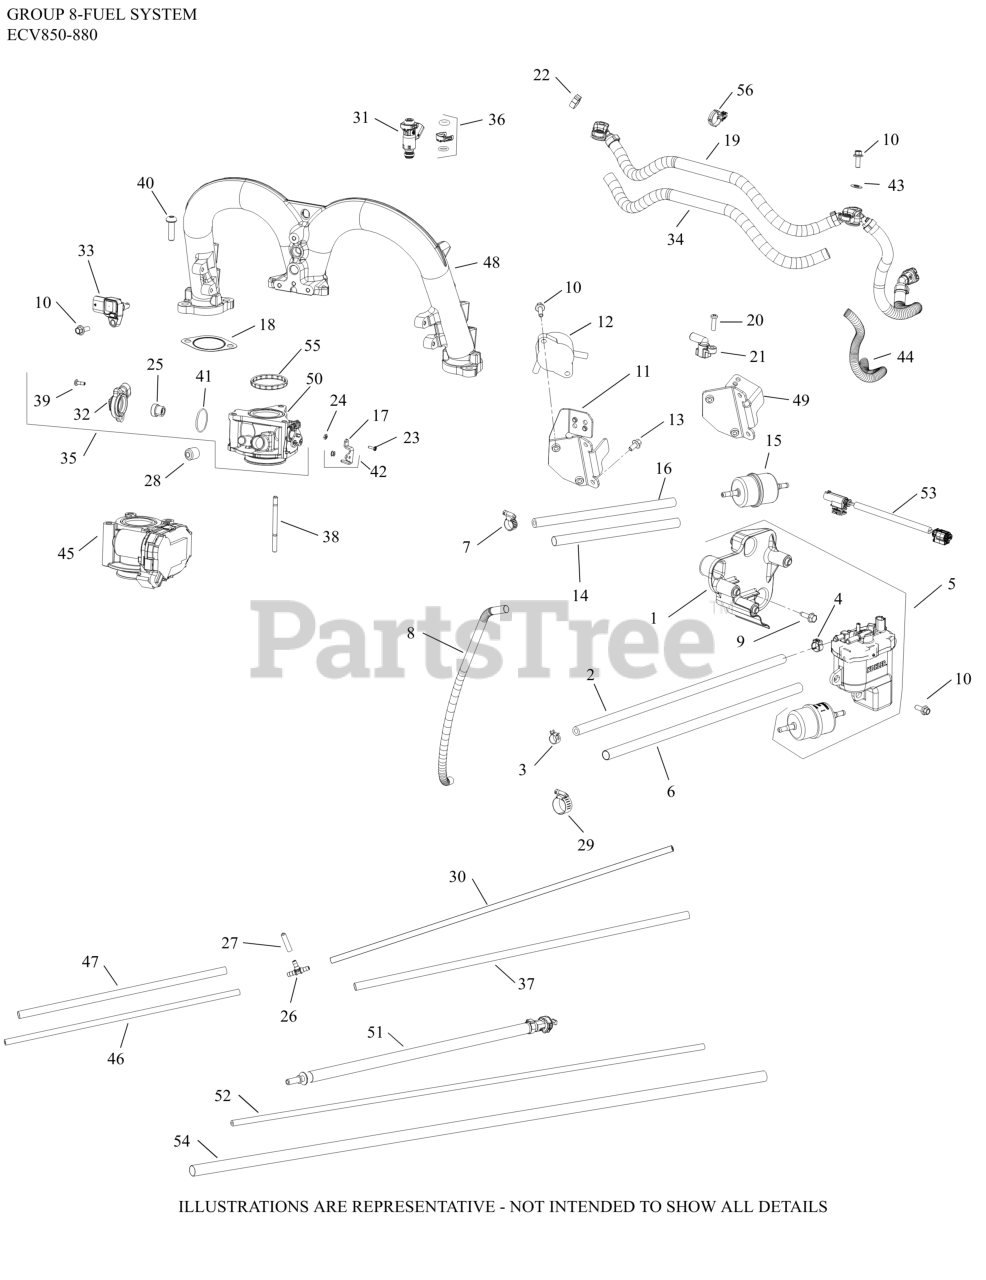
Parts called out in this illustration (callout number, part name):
1	BAFFLE, FUEL PUMP
3	SPRING CLAMP, HOSE
4	CLAMP, OETIKER
5	KIT, FPM W/BRCKT (ECV850-880)
7	CLAMP, HOSE (KM)-USE 25 237 31-S
8	SLEEVE, ANTI-ABRASION
9	SCREW, THREAD FORMING
10	SCREW, FLG M6X1.0X16
11	BRACKET, PULSE PUMP
12	PUMP, FUEL
13	SCREW, FLG M6X1.0X12
14	SLEEVE, ANTI ABRASION -USE 25 431 12-S
15	FILTER, FUEL
16	HOSE,LW PERM.FUEL 24.00"-USE 25 111 81-S
18	GASKET, INTAKE MANIFOLD
19	RAIL, FUEL - ASSEMBLY (ECV850-880)
22	CLAMP, HOSE
25	MAGNET ASSEMBLY, TPS
26	TEE CONNECTOR
27	CAP, MASKING
28	CAP, MASKING
30	HOSE, EVAPORATIVE 20"- (#24326143S)
31	INJECTOR, FUEL
32	SENSOR, THROTTLE POSITION
33	SENSOR, T-MAP
34	SLEEVE, ANTI ABRASION
35	BODY, THROTTLE ASM (30)
36	KIT, FUEL INJECTOR O-RING
37	SLEEVE, ANTI ABRASION
38	STUD,M6X1.0X84
40	SCREW, M8 x 30 PAN HD, TORX DRIVE
41	O-RING, TPS SENSOR
43	CLIP, RETAINER
44	SLEEVE, ANTI ABRASION
48	MANIFOLD, INTAKE EFI
